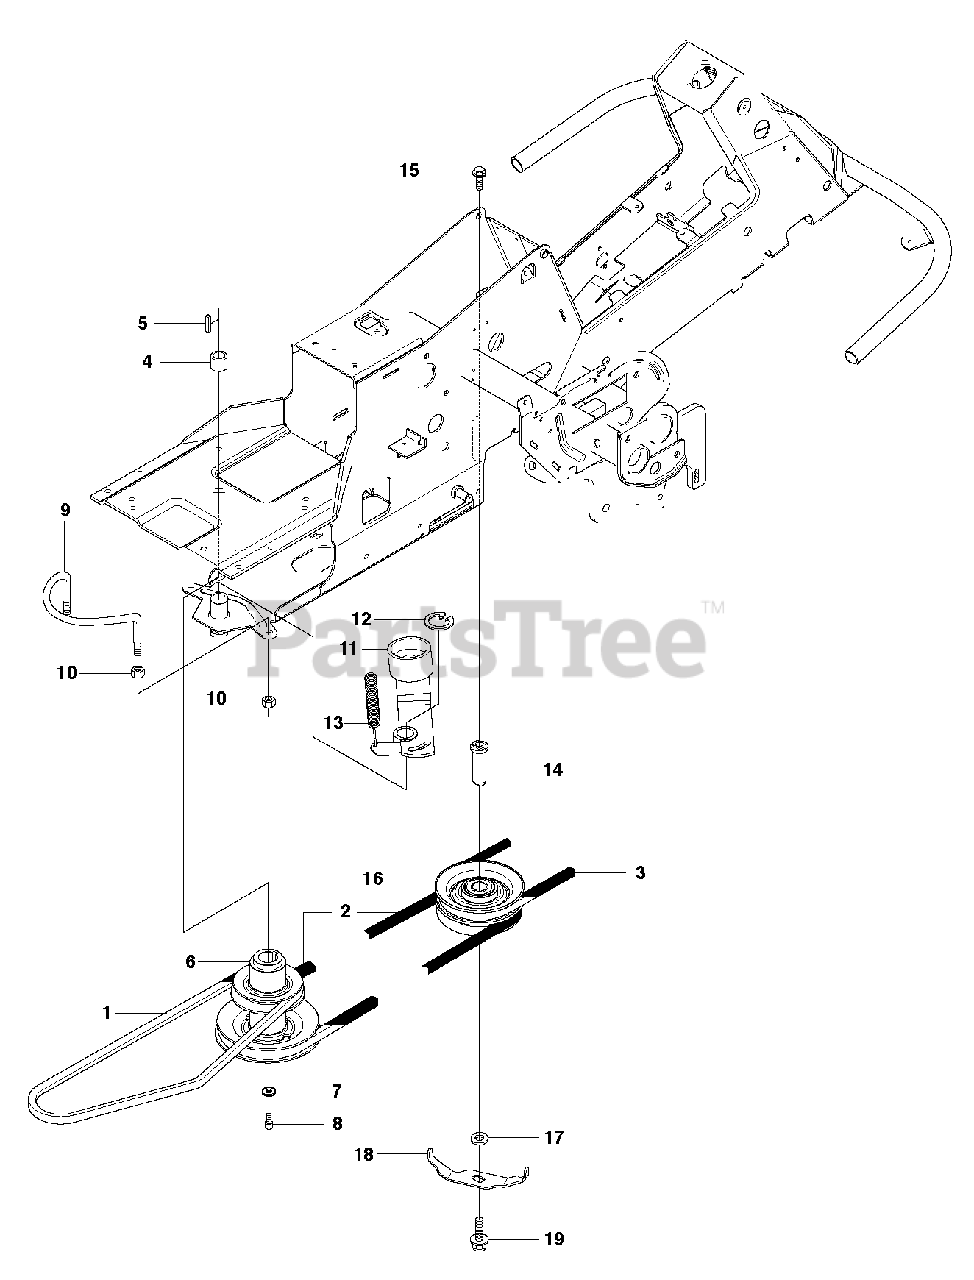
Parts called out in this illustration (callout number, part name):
1	BELT
2	BELT
9	BELT GUIDE
11	TENSIONER
12	RETAINING RING SGA 25
14	SHAFT
18	BELT GUIDE
19	BOLT
